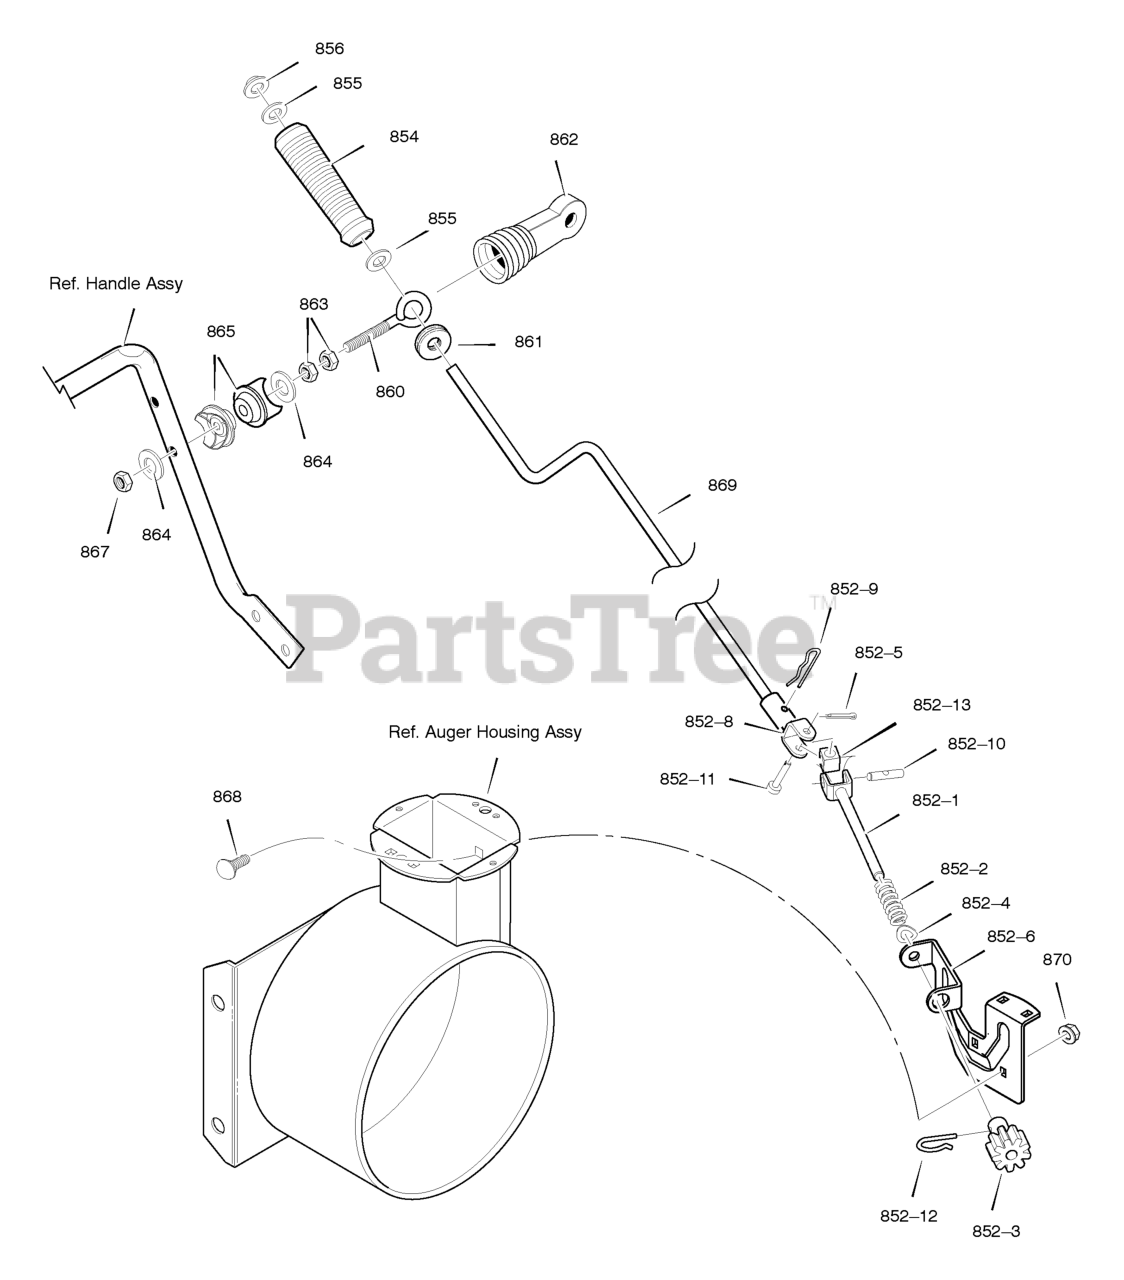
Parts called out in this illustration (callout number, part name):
852-1	ASSEMBLY, YOKE & ROD
852-3	GEAR, CHUTE ROTATION 9T
852-4	WASHER, SPRING
852-5	PIN, COTTER
852-6	BRACKET, CHUTE GEAR
852-7	PIN, HAIR
852-8	ASSEMBLY, YOKE ADAPTER YZ
852-9	PIN, HAIR
852-10	PIN, UNIVERSAL JOINT
852-11	PIN, CLEVIS
852-13	HOUSING, UNIVERSAL
854	KNOB, SLEEVE
855	FLATWASHER
856	NUT, PUSH ON 3/8"
860	EYE BOLT 3/8-16X6.50
861	GROMMET, EYE BOLT
862	BOOT, EYE BOLT
863	NUT, 3/8-16 HEXJAM
864	FLATWASHER .406X.81X.066
865	ADAPTER, BOOT
867	NUT, 3/8-16 HEXNYL
868	BOLT, CARRIAGE 1/4-20 X 1.00
869	NUT, 1/4-20
870	CRANK, ASSY CHUTE
